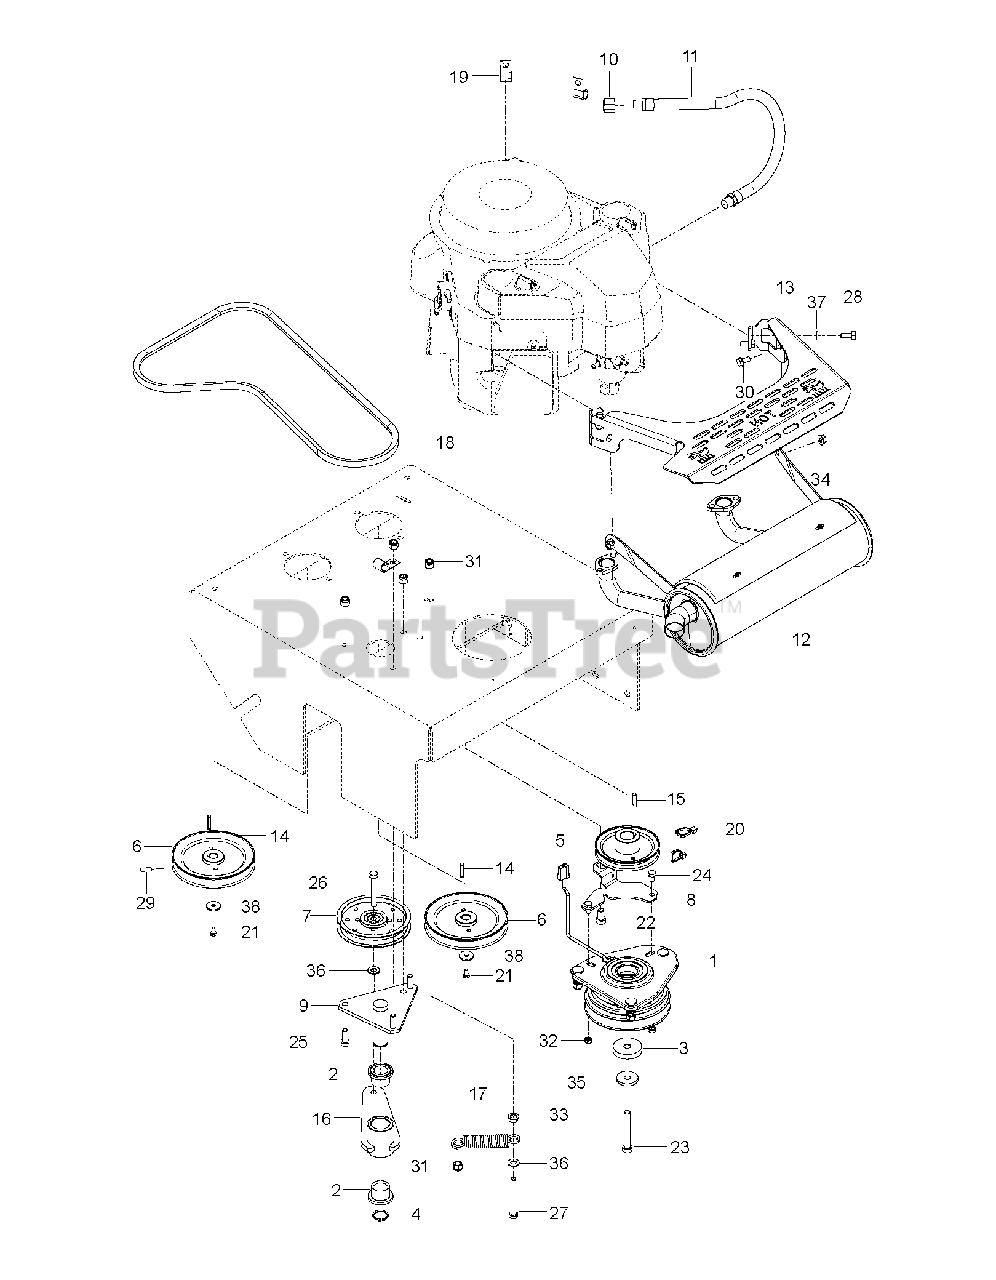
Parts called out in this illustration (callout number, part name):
1	CLUTCH CLUTCH ASSY, OGURA# GT1
2	BEARING BRG, FLG 1.00 X 1.25 X
3	SPACER SPACER, .450 X 2.00 X .
4	SNAP RING SNAP RING 1.00 X .04
5	PULLEY V-BELT WLK TRANS DRIVE
6	PULLEY V-BELT PUMP HYD WLK 73
7	Flat Pulley, 4.50 X .375 with Bearing
8	PLATE CLUTCH DOG 203840
9	MOUNT WLDT IDLER PIVOT MOUNT 2
10	CAP PIPE CAP 3/8 NPT FEMALE
11	NIPPLE DRAIN, M20 OIL
12	MUFFLER KAW FS PROWALK 4375200
13	SHIELD MUFFLER SHIELD 5132747
14	KEY M5 X M5 X M30 RD KEY 96605
15	KEY ¼ X ¼ 1 X 1
16	ARM IDLER ARM WLDT D15032
17	SPRING EXT .900 X .135 X 4.50
18	BELT HA 55.1 EL AMD OHR D38006
19	CLIP P-CLIP, .500 INSULATED
20	CABLE TIE, .15 X 8.50 111910
23	BOLT BOLT HEX .44-20 X 3 GR8
25	BOLT BOLT HEX .38-16 X 1.00 GR
26	BOLT BOLT-HEX .38-16X2.50 GR5
29	SERVICE PARTS SYSTEM SCR,SET .
30	SCREW SCREW, HEX-FL M8 X 1.25
31	NUT NUT, 3/8-16 NYLON LOCK ARI
32	SERVICE PARTS SYSTEM NUT-LK-CT
33	NUT .375-16 WHIZ LOCK FLANGE
34	LOCK NUT LOCKNUT,M8 X 1.25,FLA
35	WASHER WASHER, 3/8" SPRING DIS
36	WASHER WASHER, FL-STL .406 X .
37	WASHER WASHER, LK .31 X .078 R
38	SERVICE PARTS SYSTEM WASHER,
